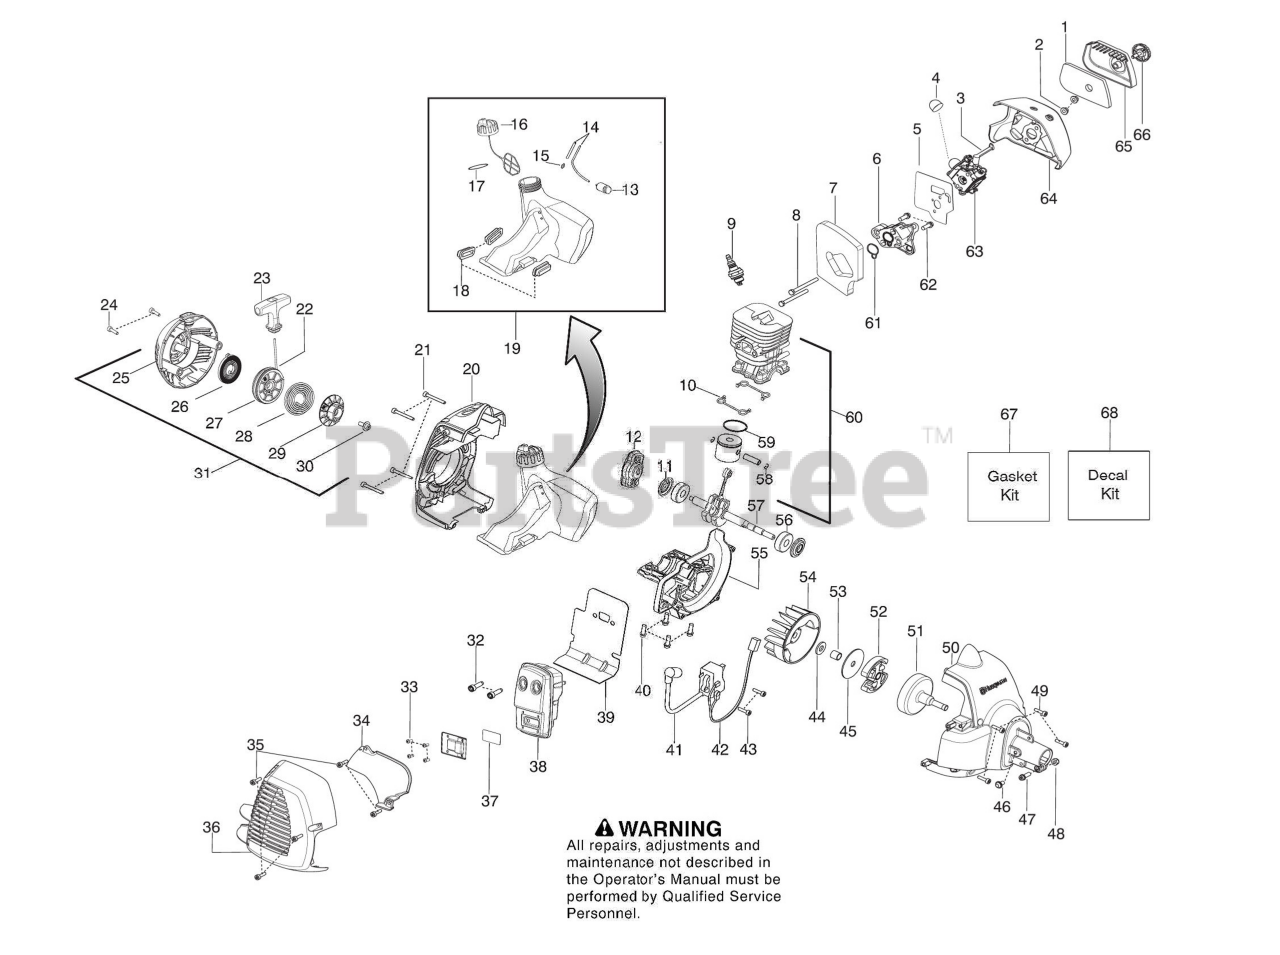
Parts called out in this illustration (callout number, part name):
2	Nut-Carb. Screw
3	Lever - Choke
4	Bulb-Purge
5	Kit-Carb. Gasket
6	Adaptor-Carb.
7	Foam-Gasket
9	Plug-Spark (RCJ-8Y)
10	Seal-Cylinder
11	Seal-Crankshaft
12	Assy-Starter Pawl
13	Assy-Fuel Filter
14	Kit-Fuel Line
15	Fitting-Fuel Line
16	Assy-Cap w/ret.
17	O-ring-Fuel Cap
18	Isolator-Fuel Tank
19	Kit-Fuel Tank Assy.
20	Shroud-Rear
22	Kit-Rope
23	Handle-Starter
25	Starter Hsg. w/eyelet
26	Kit-Spring
27	Kit-Starter Pulley
28	Spring - Driver
29	Pulley-Driver
31	Assy-Starter Hsg.
32	Bolt-Muffler
33	Screw
34	Shield-Heat
36	Guard-Muffler
37	Kit-Spark Arrestor
38	Kit-Muffler
39	Gasket-Paper met.
42	Assy-Leadwire
45	Washer-Clutch
50	Assy-Fan Housing
51	Assy-Clutch Drum
52	Assy - Clutch
55	Crankcase
57	Assy-Crankshaft
58	Retainer-Piston Pin
59	Ring-Piston
60	Kit-Piston/Cyl.
61	Kit-Gasket
63	Kit-Carb.
64	Airbox
65	Cover-Air Box
67	Kit-Gasket
